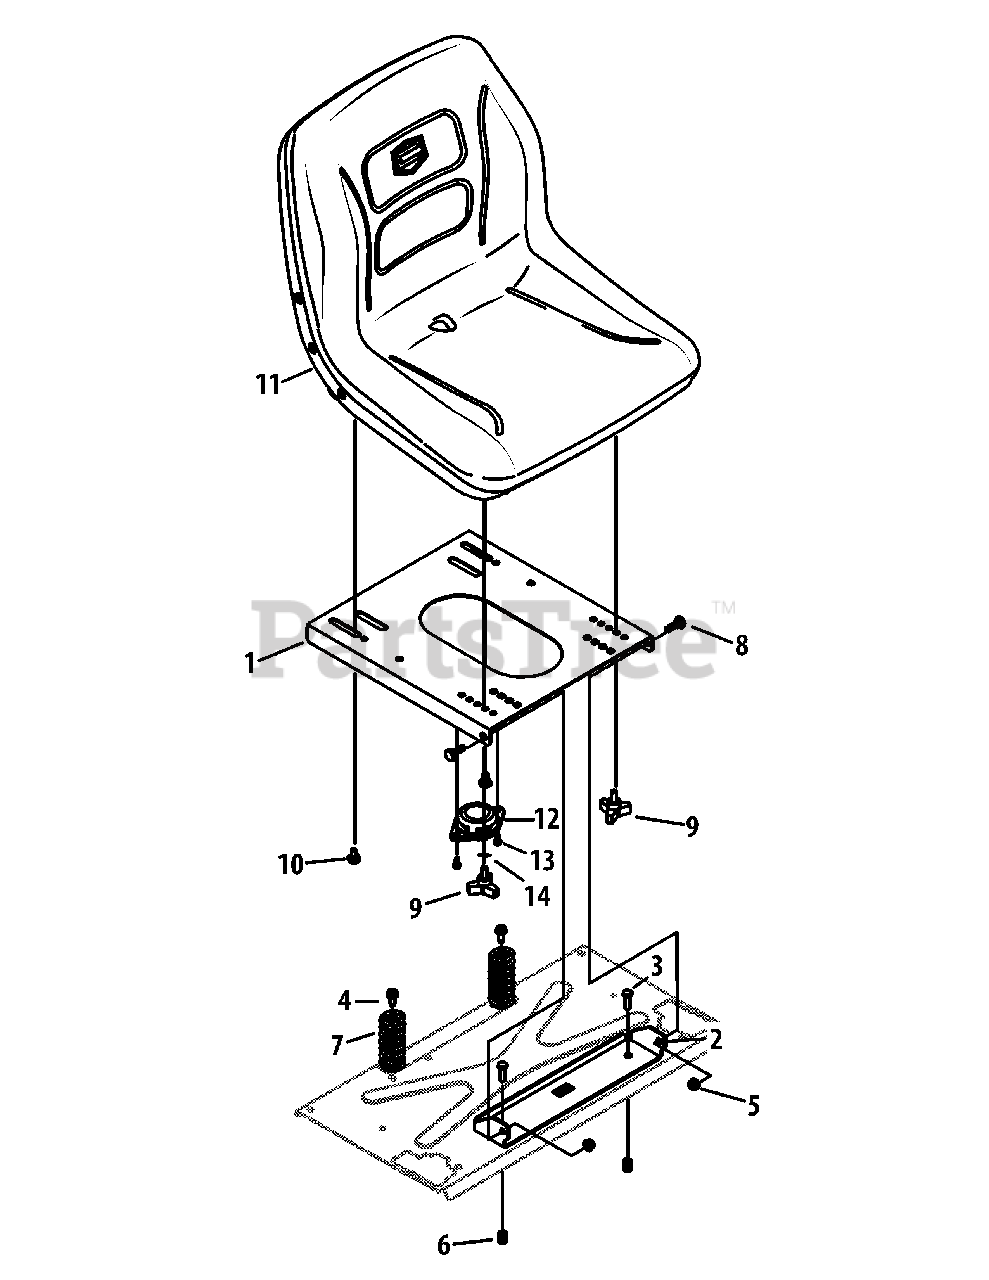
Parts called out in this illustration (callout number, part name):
1	Seat Plate
2	Seat Pivot Bracket
3	Hex Screw, 5/16-18 x 1.00
4	Hex Washer Screw, 5/16-18 x .750
5	Flange Lock Nut, 5/16-18
6	Lock Nut, 5/16-18
7	Compression Spring, 1.71 x 3.25 x .23
8	Soulder Screw, 5/16-18 x .437 x .268
9	Knob, 5/16-18
10	Shoulder Bolt, 5/16-18 x .435 x .160
12	Seat Switch
13	Hex Washer Screw, #12-16 x .50
14	Lock Washer, 5/16
